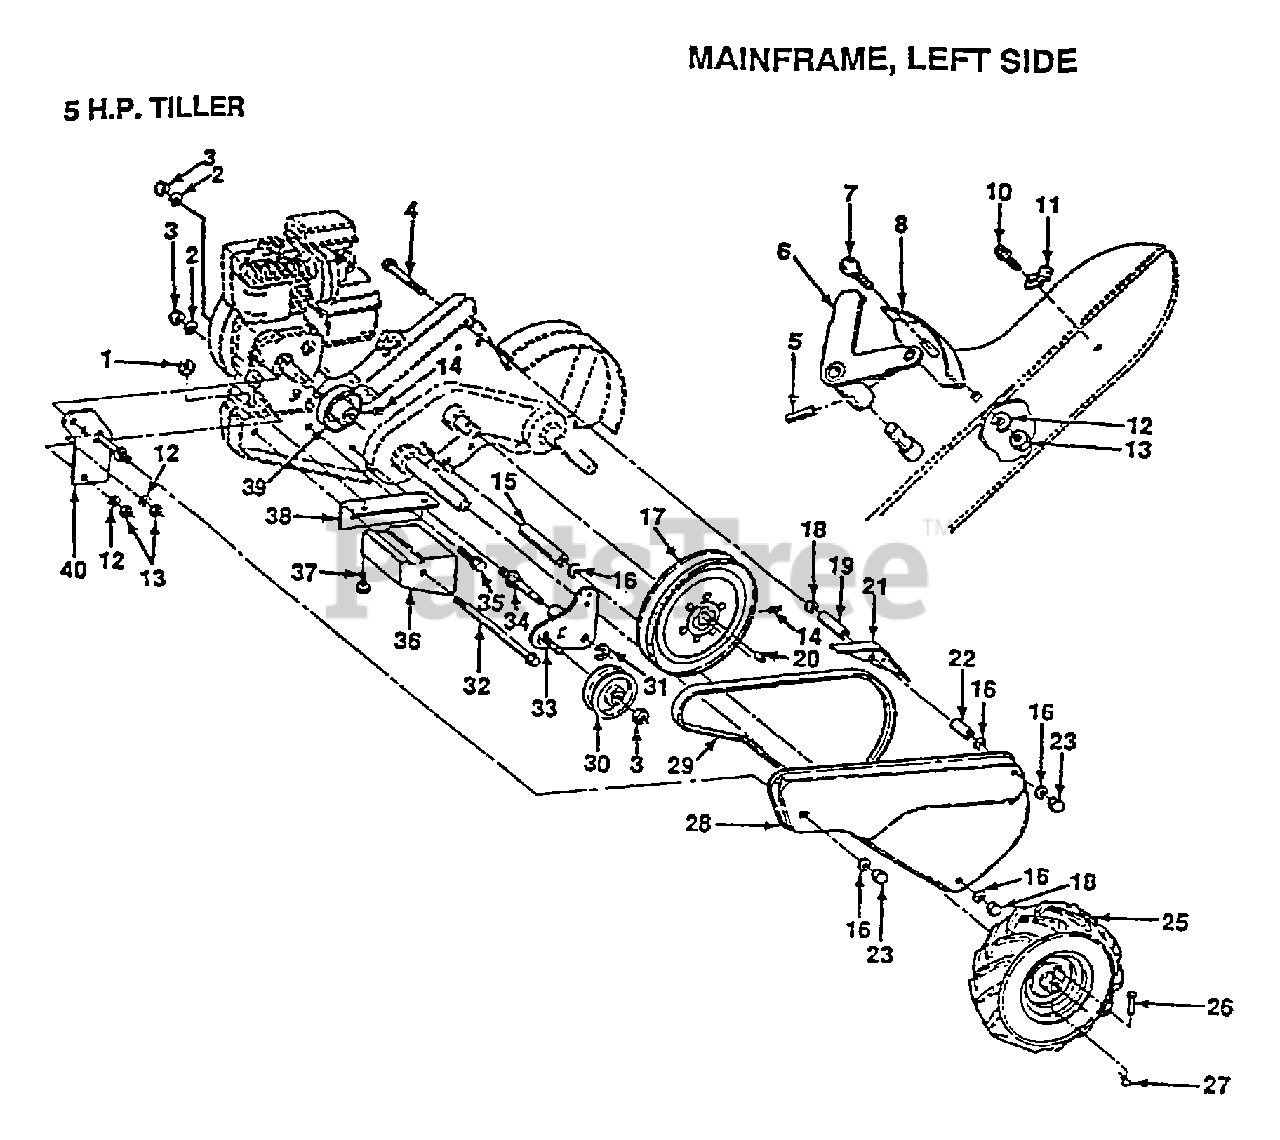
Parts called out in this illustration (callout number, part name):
2	LOCKWASHER
3	NUT.HEX.3/8-16UNC
4	BOLT-HEX TI
6	LEVER ASM CRT
7	BOLT
8	PANEL TI
11	CONDIUT CLIP T
12	LOCKWASHER
14	SET SCREW
15	SPACER
16	WASHER
17	"SHEAVE 10"" CRT"
18	NUT.HEX.5/16-18
19	SPACER CRT
20	KEY T
21	GUARD CRT
22	SPACER CRT
23	NUT TI
25	TIRE.CHV.13X5.0-6
25	RIM
26	RIVET.DRILL.1.75
27	RETAINER M
30	PULLEY-IDLER TI
31	KLIP RING
32	BOLT CRT
34	SHIFT ARM CRT
35	BOLT
36	COUNTERWEIGHT CRT
37	BOLT.HEX.5/16-1.5
38	BRACKET LH CRT
40	BRACKET ASSY CRT
